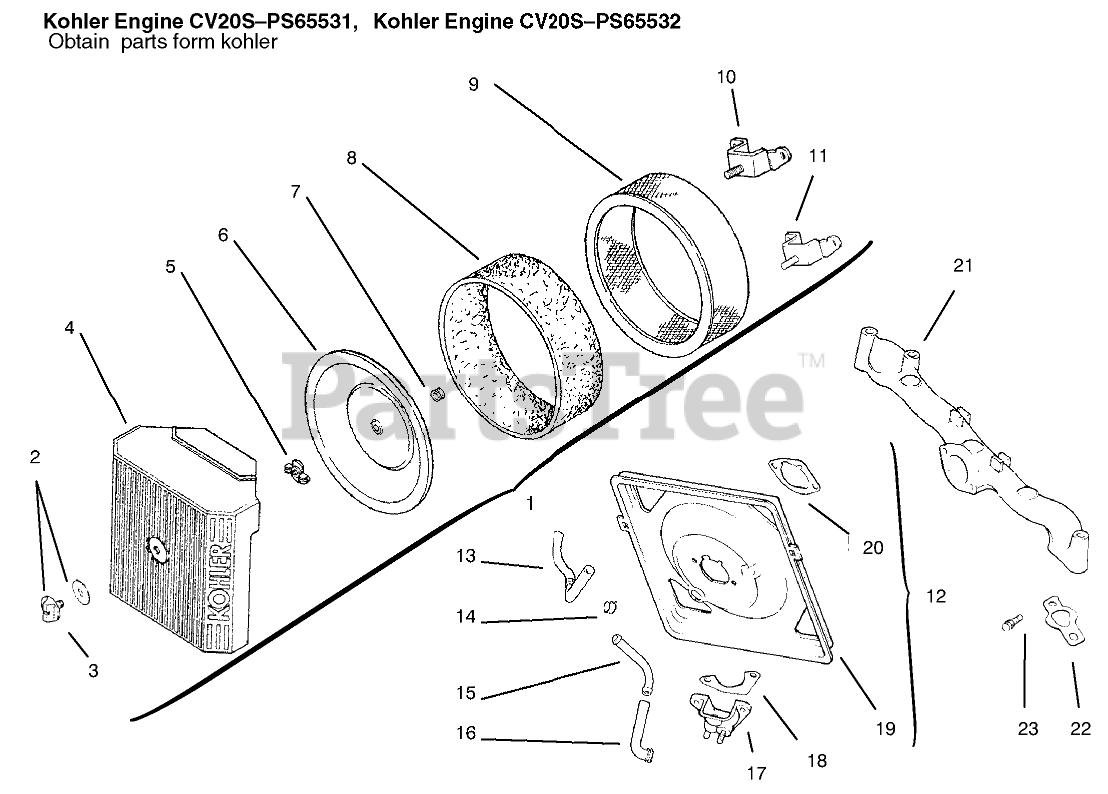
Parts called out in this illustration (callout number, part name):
1	Kit-A/C Cover INC 2-4
2	Spring-Latch
3	Latch-Lever
4	Pin-Latch Lever
5	Wingnut
6	Seal, insert
7	Cover-Inner AirCleaner
8	Bement-Precleaner
9	Bement-Air Cleaner
10	Cup-Fuel Spitback
11	Gasket-Fuel Spitback
12	Base-Air Cleaner
13	Gasket-A/C Base
14	Manifold-Intake
15	Gasket-Intake, Manifold
16	Screw
